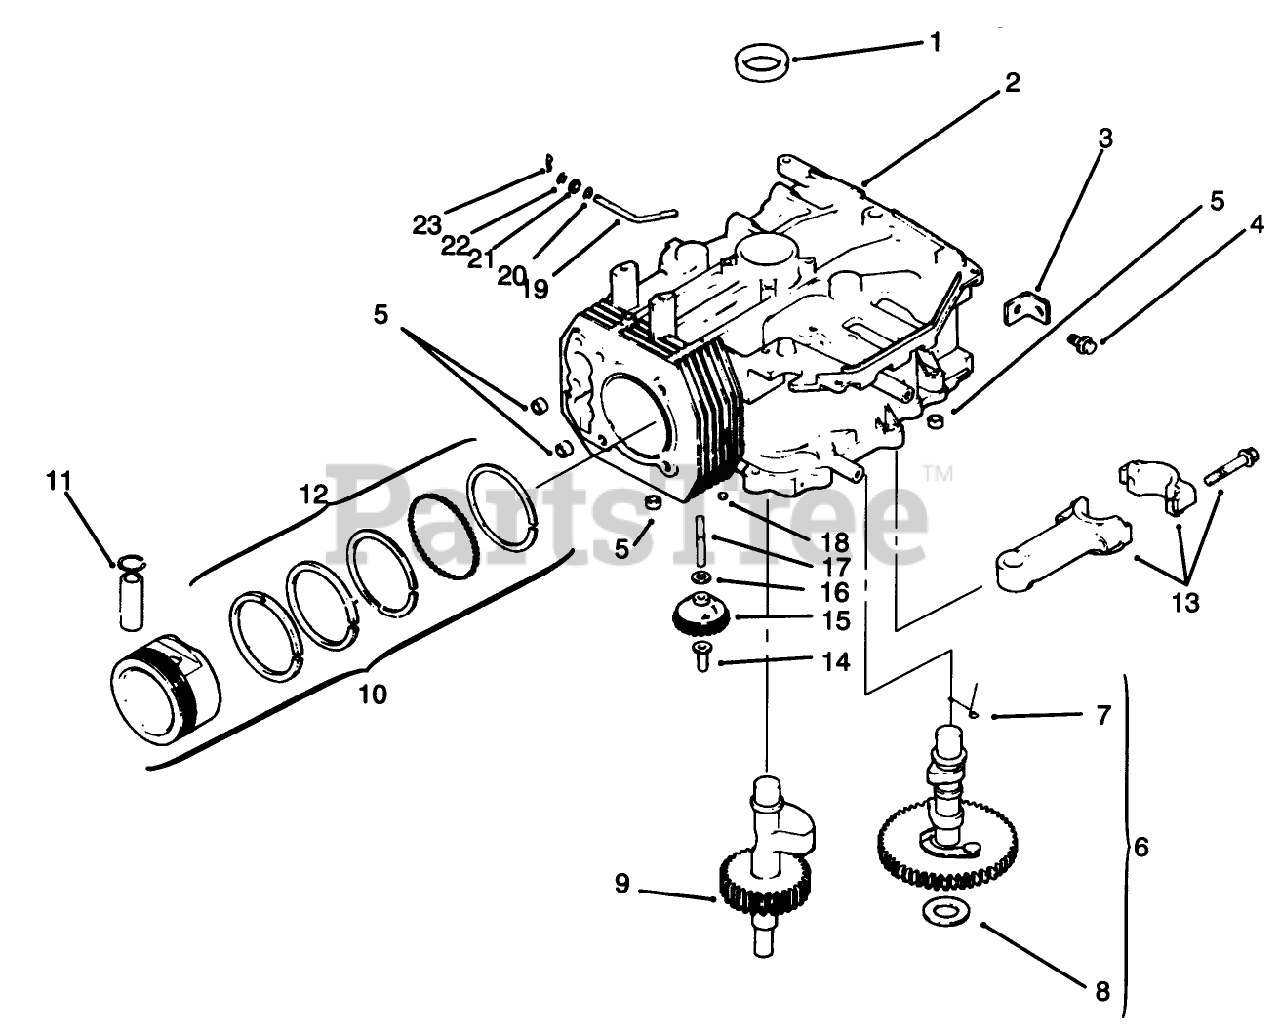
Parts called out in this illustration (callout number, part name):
1	Seal-Crankshaft (Only On: 72042, 72043, 72062, 72063)
3	Strap-Lifting (Only On: 72042,72043,72062,72063)
4	Screw M8x1.25x22 (Only On: 72042, 72043, 72062, 72063)
5	Pin-Dowel
6	Kit-Camshaft INC 7-8 (Only On: 72042, 72063, 72062, 72043)
7	Spring-Actuating (Only On: 72042,72043,72062,72063)
8	Shim-Camshaft
9	Shaft-Balance (Only On: 72042, 72043, 72062, 72063)
10	Piston ASM STD INC 11-12 (Only On: 72042, 72063, 72062, 72043)
10	Piston ASM .25 INCL 11-12 (Only On: 72042,72043,72062, 72063)
10	Piston ASM .50 INCL 11-12 (Only On: 72042, 72043, 72062, 72063)
11	Retainer-Piston Pin (Only On: 72042, 72043,72062,72063)
12	Ring Set STD (Only On: 72042,72043,72062,72063)
12	Ring Set .25 (Only On: 72042,72043,72062,72063)
12	Ring Set .50 (Only On: 72042,72043,72062,72063)
13	Connecting Rod STD (Only On: 72042, 72063, 72062, 72043)
13	Connecting Rod .25 (Only On: 72042, 72063, 72062, 72043)
14	Pin-Governor
15	Gear-Governor ASM (Only On: 72042, 72063, 72062, 72043)
17	Shaft-Govenor Gear
19	Shaft-Governor Cross (Only On: 72042, 72063, 72062, 72043)
20	Washer-Governor Shaft (Only On: 72042, 72063, 72062, 72043)
21	Seal
22	Washer
23	Pin-Hitch
